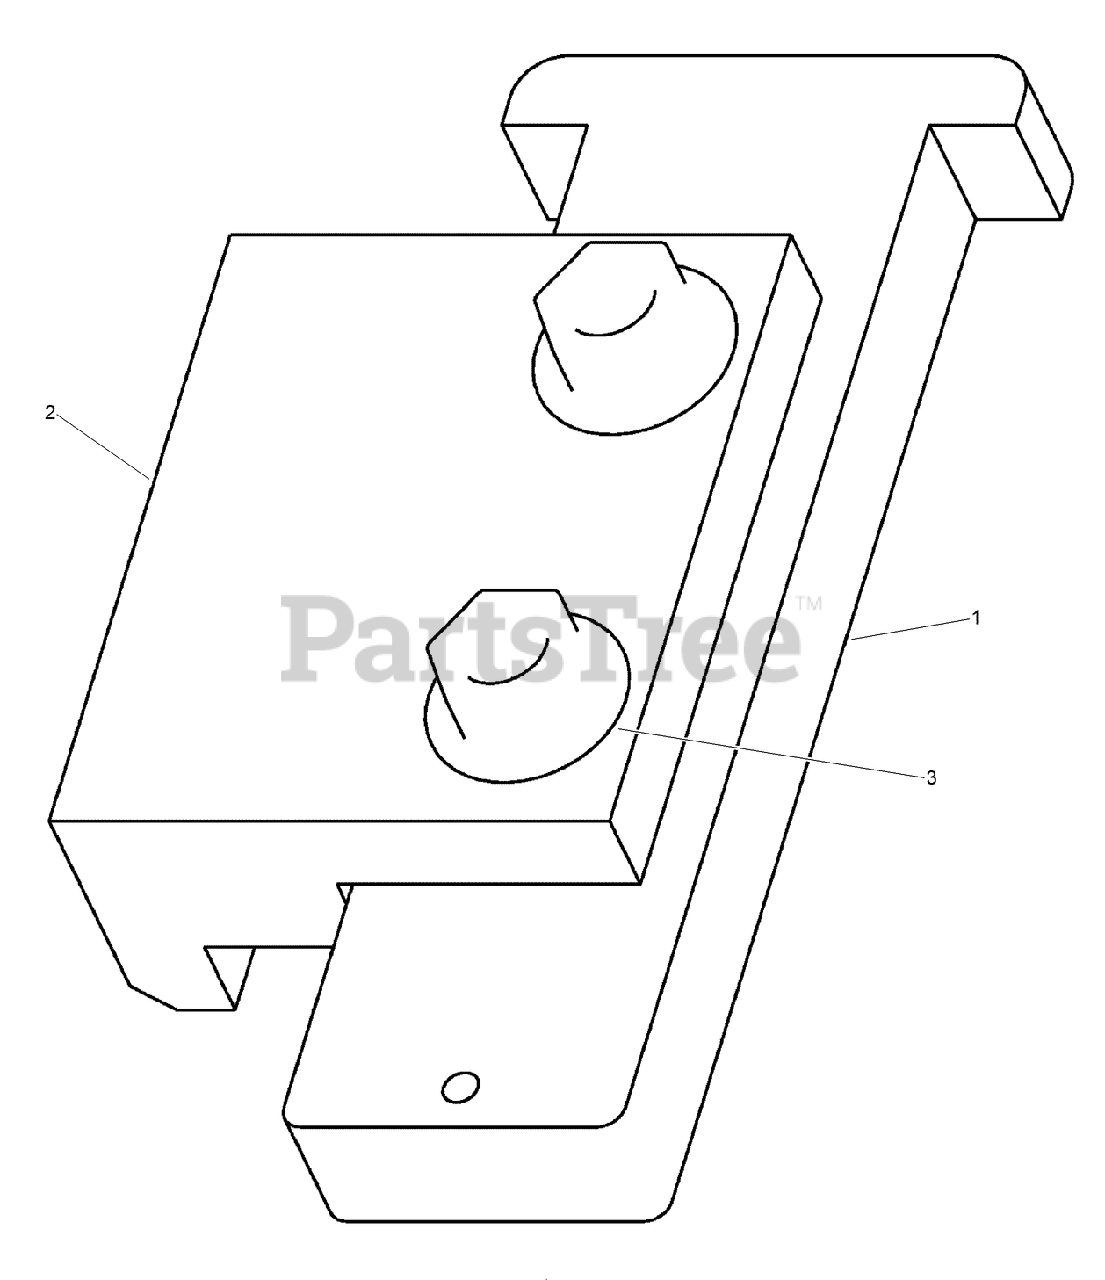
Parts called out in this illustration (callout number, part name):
1	PIN - Retaining
2	BLOCK-STOP, CYLINDER
3	SCREW, METRIC FLANGE w/BODY-M12 x 30
